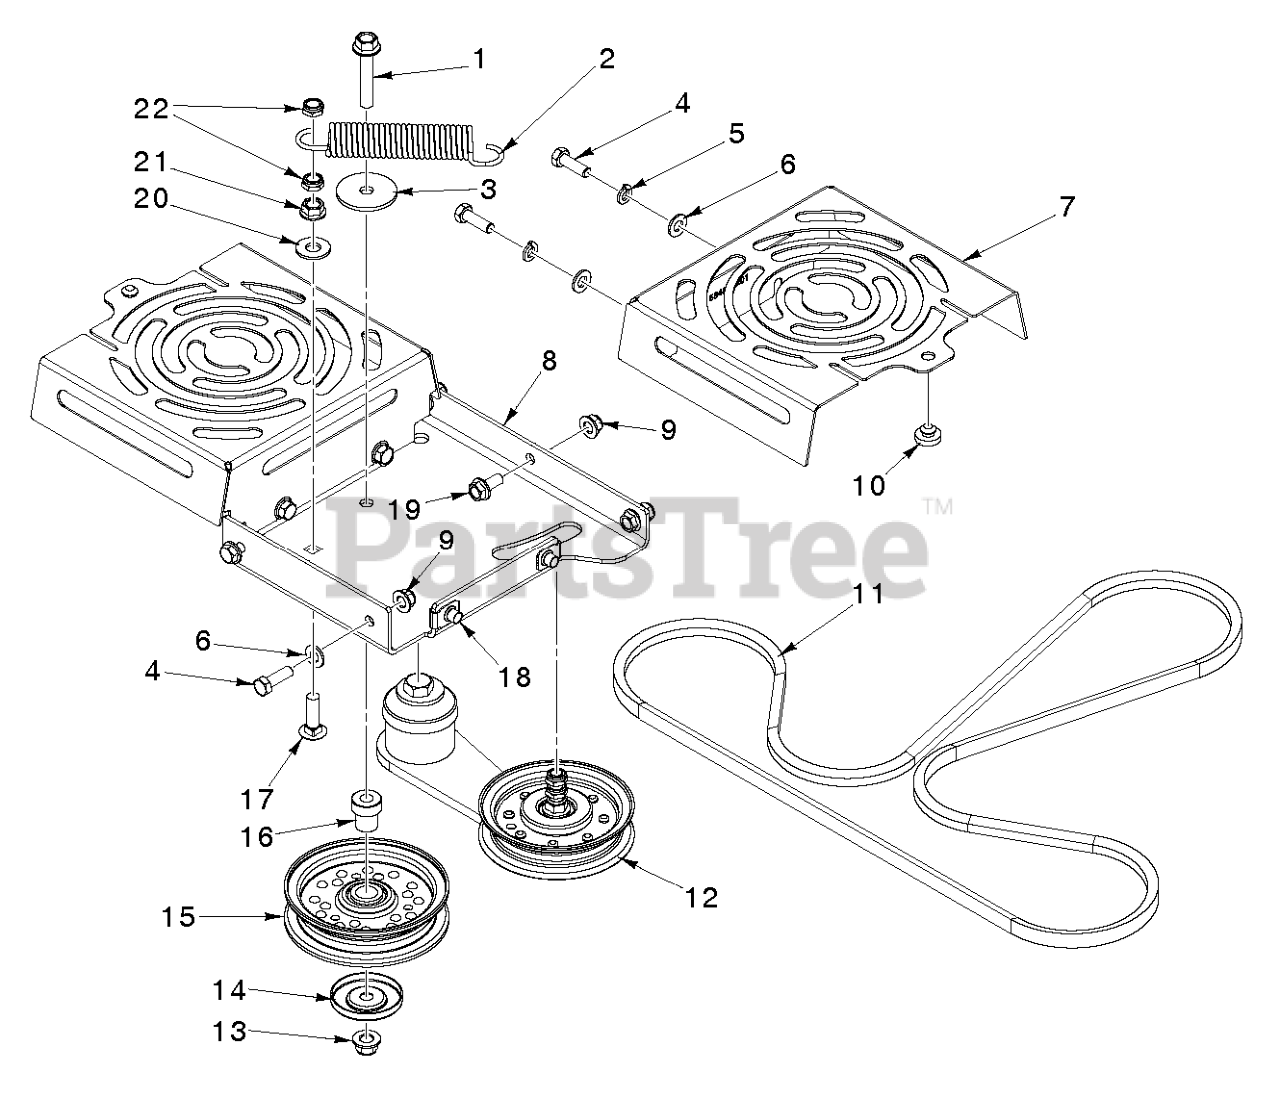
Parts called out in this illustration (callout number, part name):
5	WASHER SPRING LOCK WASHER WITH
6	WASHER 11/32 X 11/16 X 14 GA T
7	SHIELD FAN BLACK
8	PLATE.PNT.IDLER.SUPPORT.E-DIP
9	NUT HEXAGON FLANGE 5/16-18 ST
10	GROMMET, BUMPER
11	BELT, HYDRO, 3400
14	SHIELD DUST
16	PIVOT, IDLER
18	U-CLIP 5/16-18 NUT RETAINER
20	GSPW Washers
